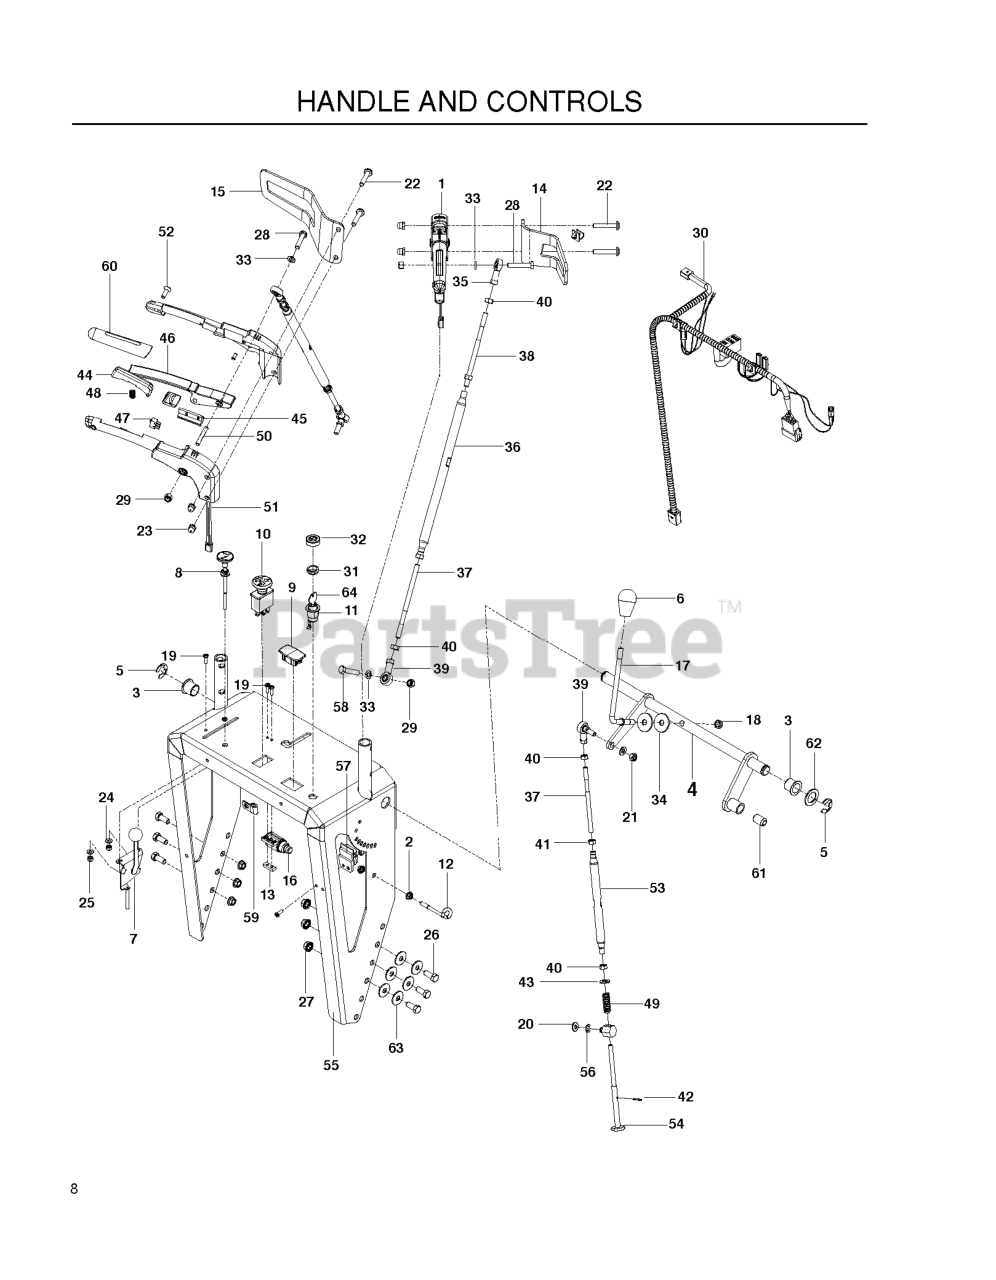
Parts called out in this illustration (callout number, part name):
2	NUT 5/16C WHIZ
3	BEARING - FLANGE, 20MM
4	SHAFT, SPEED CONTROL
5	E-RING, 20MM
6	KNOB - SHIFT
7	THROTTLE CONTROL
8	CONTROL-CHOKE 51"
9	PLUG DASH
10	RP.SWITCH, BLADE
11	KEY SWITCH, COMPLETE
12	GUIDE - ROPE
13	TAPPED PLATE
14	GUARD, HAND - OFFSET RH, PTD
15	GUARD, HAND - OFFSET LH, PTD
16	SWITCH, NO PLUNGER TYPE
17	ROD - SHIFT
18	NUT HEX 3/8-16 NYLON, THIN
19	HCS #10-24 X 1/2
20	WASHER 3/8 SAE FLAT
21	NUT M8-1.25 TOP NYL GR10 ZD
22	HHFS 5/16-18 X 1.75 GR8 ZC
23	NUT ACORN 5/16-18
24	WASHER #10
25	NUT 10-24 NYLOC
26	HCS 3/8-16 X 7/8 GR 5 ZD
27	NUT 3/8C WHIZ
28	HCS 5/16C X 1 3/4
29	NUT 5/16 NYLOC
30	HARNESS, UPPER HANDLE
31	DNO IGNITION NUT
32	CAP IGNITION NUT
33	WASHER.LOCK.HVY.HLCL.SPR.5/16
34	CONE WASHER
35	ROD END 8 MM, RH
36	TUBE - ADJUSTING
37	STUD - LH
38	STUD - RH
39	ROD END 8 MM, W/STUD
40	NUT 8MM X 1.25 HEX ZD
41	NUT, 8MM X 1.25 LEFT HAND
42	ROLL PIN - 3 MM
43	WASHER, 10MM
44	OPC ACTUATOR
45	LOCK - NEUTRAL
50	PIN - GROOVE 1/4 X 1-1/2
51	HARNESS - SWITCH
52	SCREW - OVAL HEAD 6MM
53	TUBE - ADJUSTING
54	ROD - HEADED
55	HANDLE W/DECAL
56	E-RING, 10MM
58	BOLT, TAP 5/16-18
59	DOUBLE TUBE CLAMP
60	GRIP, FOAM
62	BSHG .875 X 1.375 X .074 ZD
63	SPRING WASHER - .38
64	KEY-PADDED
